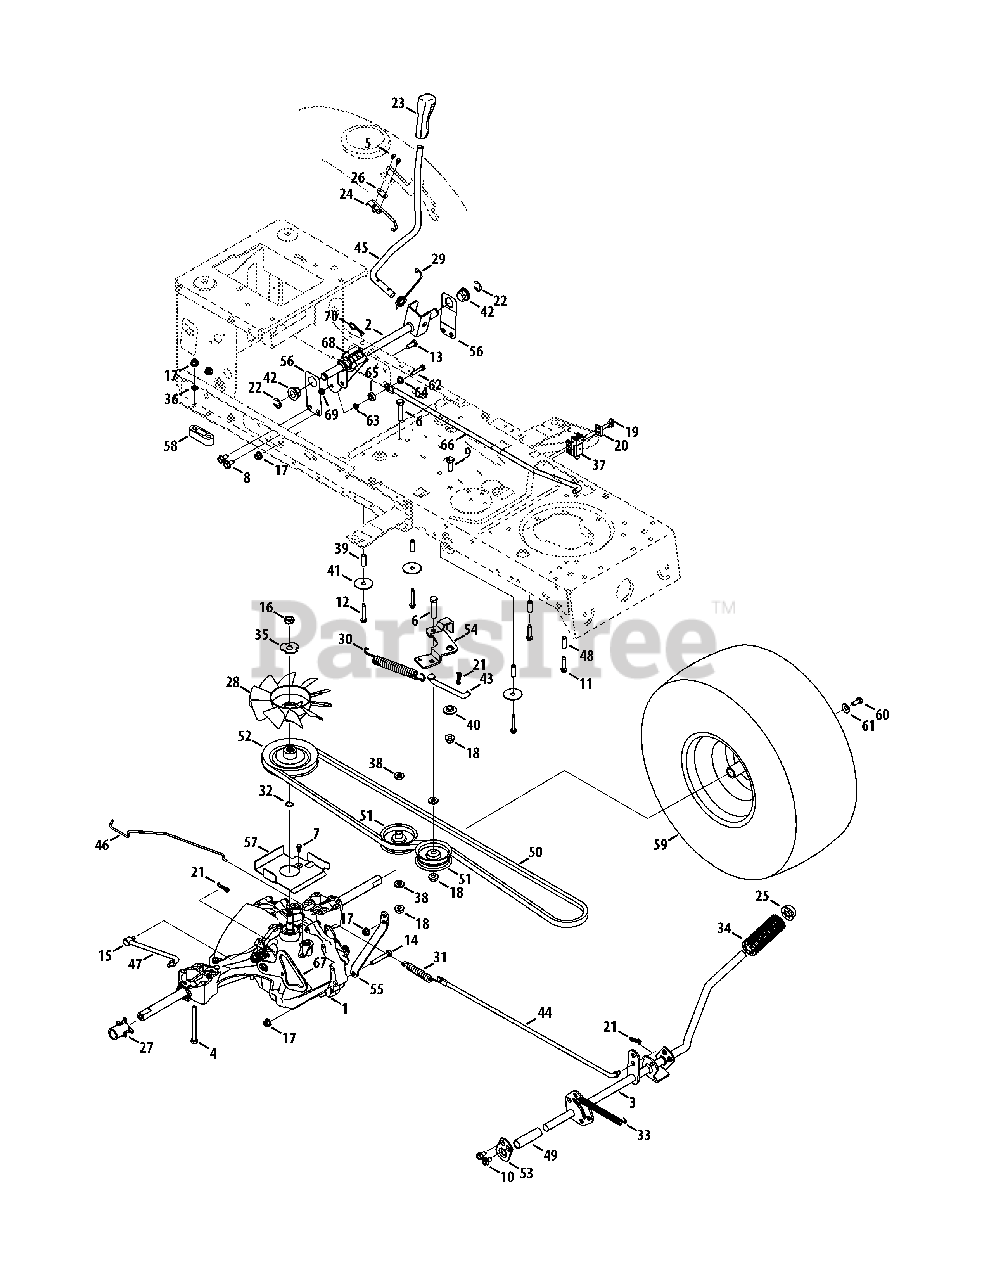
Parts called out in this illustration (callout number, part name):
1	Hydro Transmission
2	Hydro Handle Control Assembly
5	Screw, #8-18:0.500
6	Hex Screw, 3/8-16:1.75
7	Screw, #10-16:0.500
8	Screw, 5/16-18:.750
9	Hex Screw, 3/8-16:1.00
10	Screw, 5/16-18:0.625
11	Screw, 1/4-20:1.250
12	Screw, 1/4-20 x 1.75
13	Hex Screw, 5/16-18:.75
14	Screw, 5/16-18 x 2.00
15	Ferrule, 5/16-24 X .312 DIA.
16	Jamlock Nut, 1/2-20
17	Flangelock Nut, 5/16-18
18	Flangelock Nut, 3/8-16
20	Plate Switch
21	Cotter Pin, Bow Tie
22	E Rign, .625 DIA
23	Handle Grip
24	Hydro Spring Switch
25	Push Cap, 5/8
26	Insulator Plate Nut
27	Sleeve, .765 ID X 2.11 LG
28	Hydro Fan
29	Torsion Spring
30	Extension Spring, .75 DIA. X 6.02
31	Extension Spring, .59 OD X 4.00 LG
32	Wire Ring
33	Extension Spring, .50 DIA X 6.37 LG
34	Foot Pad, 4.0
35	Lock Washer, TRANS HYDRO
36	Lock Washer, 5/16 EXT TOOTH
37	Switch Interlock
38	Flat Washer, .407X.812X.135:HT
39	Spacer, .260 x .372 x 1.420
40	Shldr Spacer, 1.375 ID X .380 x 1.54
41	Flat Washer, .350 x 1.59 x .062
42	Hex Flange Bearing
43	Declutching Rod
44	Brake Rod
45	Hydro Control Handle
46	Hydro Bypass Rod
47	Hydro Control Rod
48	Spacer, .260 x .375 x 1.030 LG
49	Spacer, .640 ID X .76 OD X 2.63
50	V Belt, 4L SEC X 84.17
51	Flat Idler Pulley 2.75 OD
52	Input Pulley
53	Support Pedal Bracket
56	Handle Bracket
57	Belt Support Bracket
58	Spacer, T-Axle
59	Wheel, 20 x 8 x 8 - Grey
59	Wheel, 20 x 8 x 8 - Yellow
60	Hex Screw, 5/16-24 x .750
61	Bell Washer, .340 x .872 x .060
62	Hex Screw, 1/4-20 x 1.25
63	Flat Washer, .281 x .500 x .063
64	Shoulder Spacer, .375 x .625 x .20
65	Ball Bearing, .25 x .6875 x .25
66	Hydro Rod, RTN
69	Nut, Flange Lock, 1/4-20, GrF
70	Click Pin, .092 x 1.64 LG
